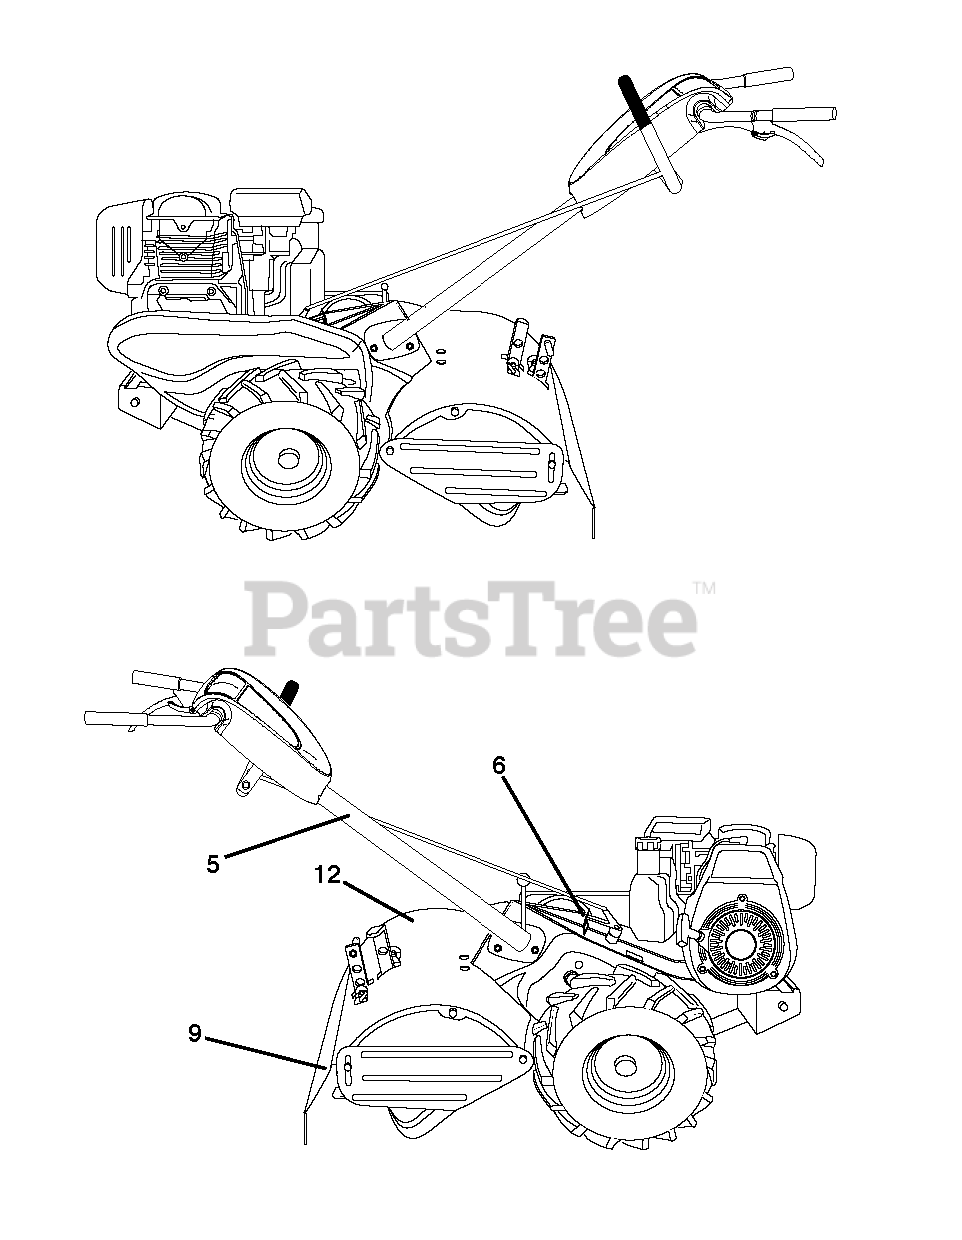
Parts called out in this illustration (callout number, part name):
5	DECAL TI (2 2)
6	DECAL.SHIFT.INDICATOR.DRT
9	DECAL.DRT.WARN.ENG/F
12	DECAL TILLER TINE SHIELD GRAPH
